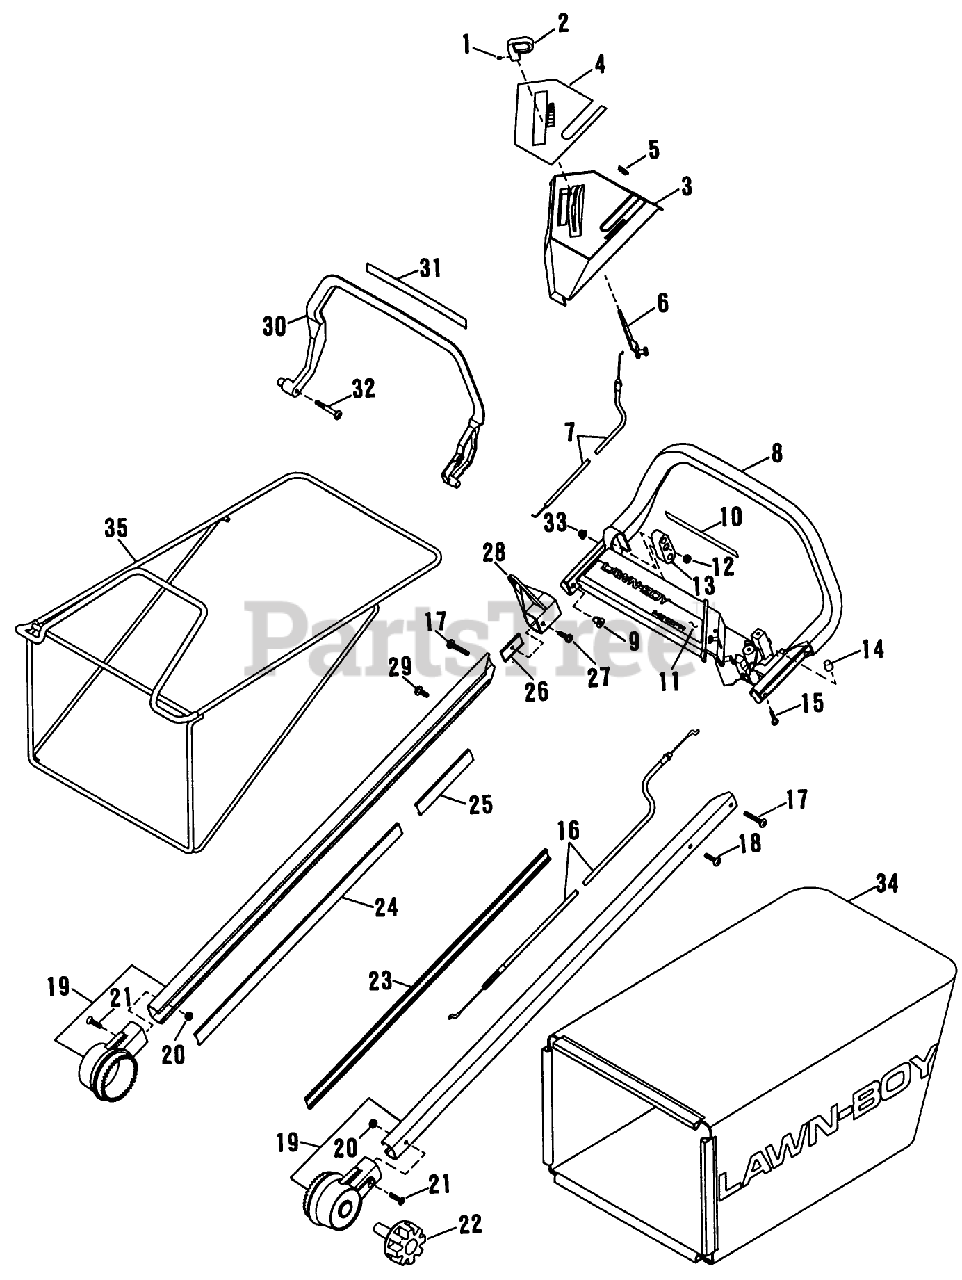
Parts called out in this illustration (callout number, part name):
7	CABLE
12	LOCKNUT E
13	BLOCK BAIL PL
16	CABLE ASSEMBLY
17	SCREW-TRUSS
18	SCREW-CROSS RECESS
20	LOCKNUT FLAN
22	KNOB-HDLE MT.ASM*B
26	NUT LB
33	LOCKNUT FLAN
34	REPL BAG FOR 684190
